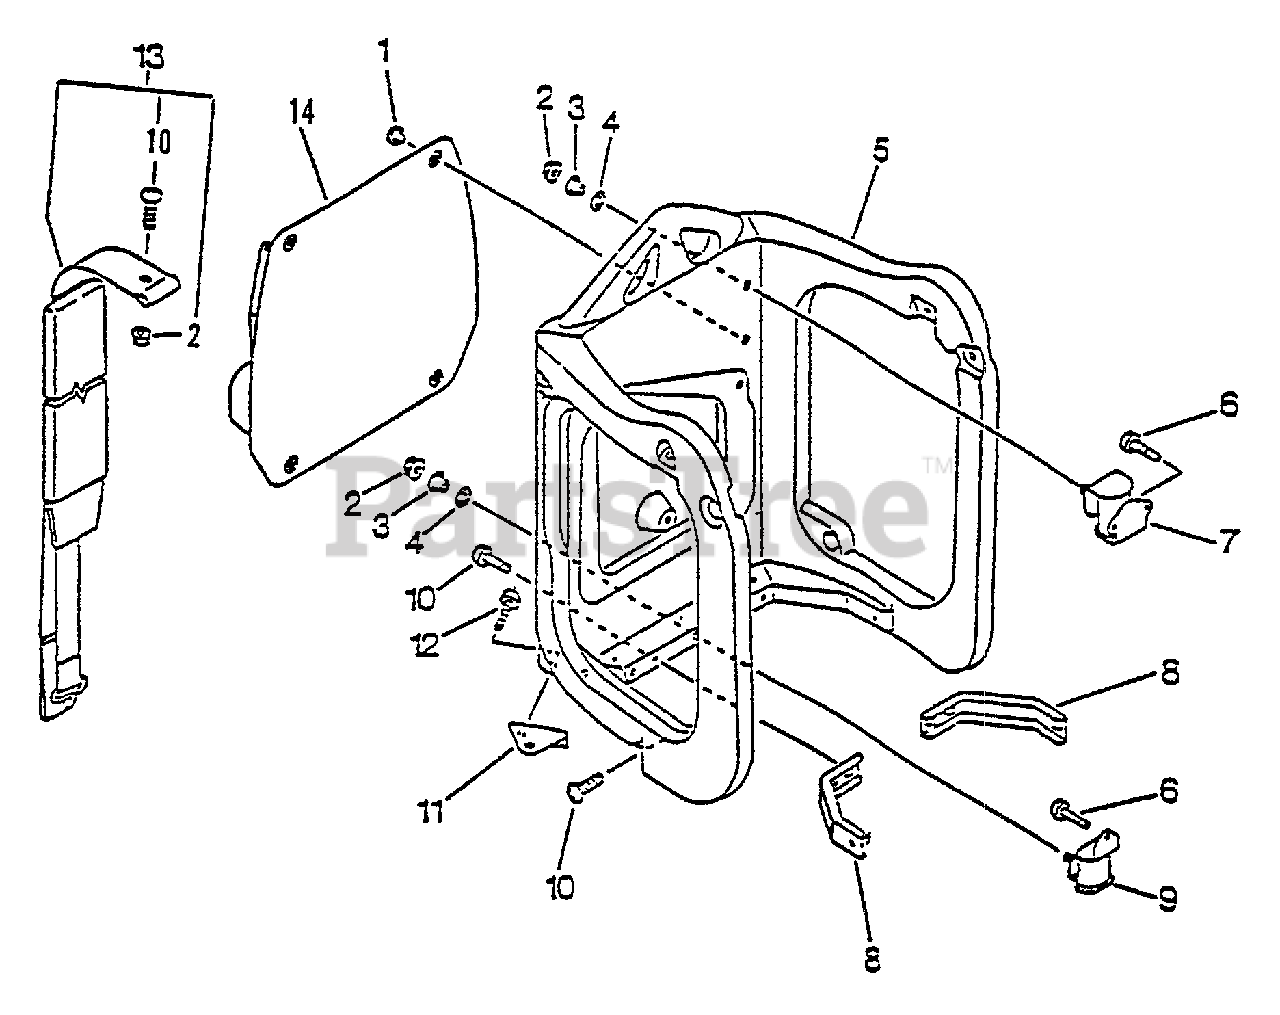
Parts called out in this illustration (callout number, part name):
2	NUT - 5 -- FLANGE
4	WASHER - RUBBER
5	FRAME, BACKPACK
6	SCREW - 5X16 -- TAPPING
8	CONNECTOR, FRAME
9	CUSHION
10	SCREW - 5X14
11	BRACKET, HANGER
12	SCREW - 5X20
13	STRAP, BACKPACK
14	CUSHION, BACKPACK
